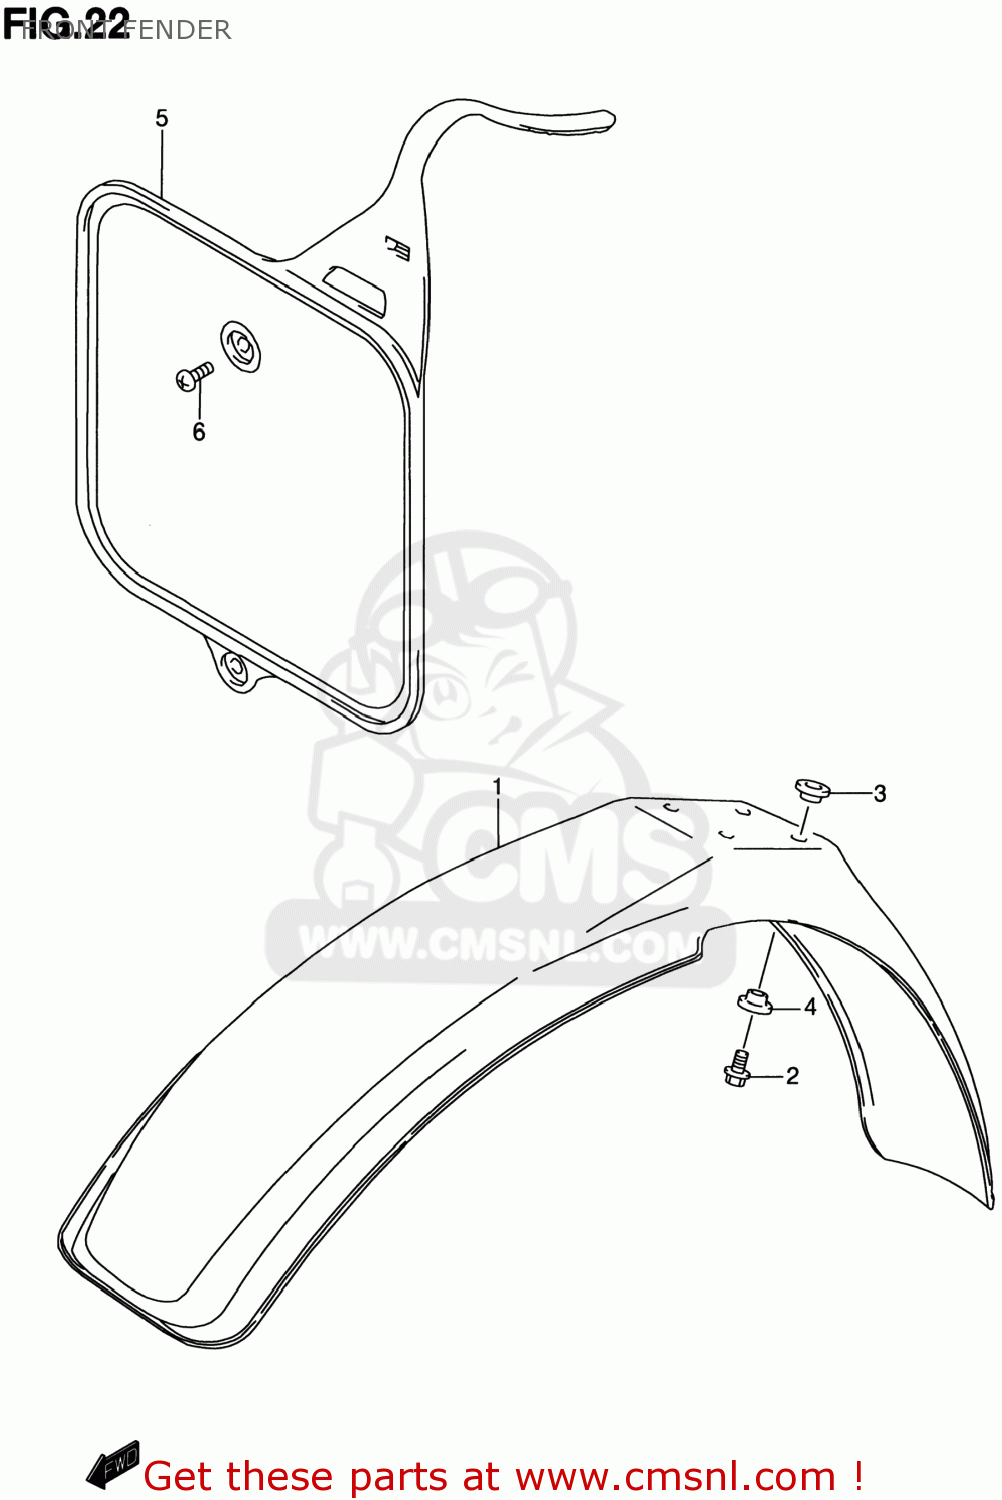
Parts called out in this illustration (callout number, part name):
1	FENDER,FRONT
2	BOLT
3	WASHER
4	WASHER
5	PLATE,NUMBER FR
6	SCREW
